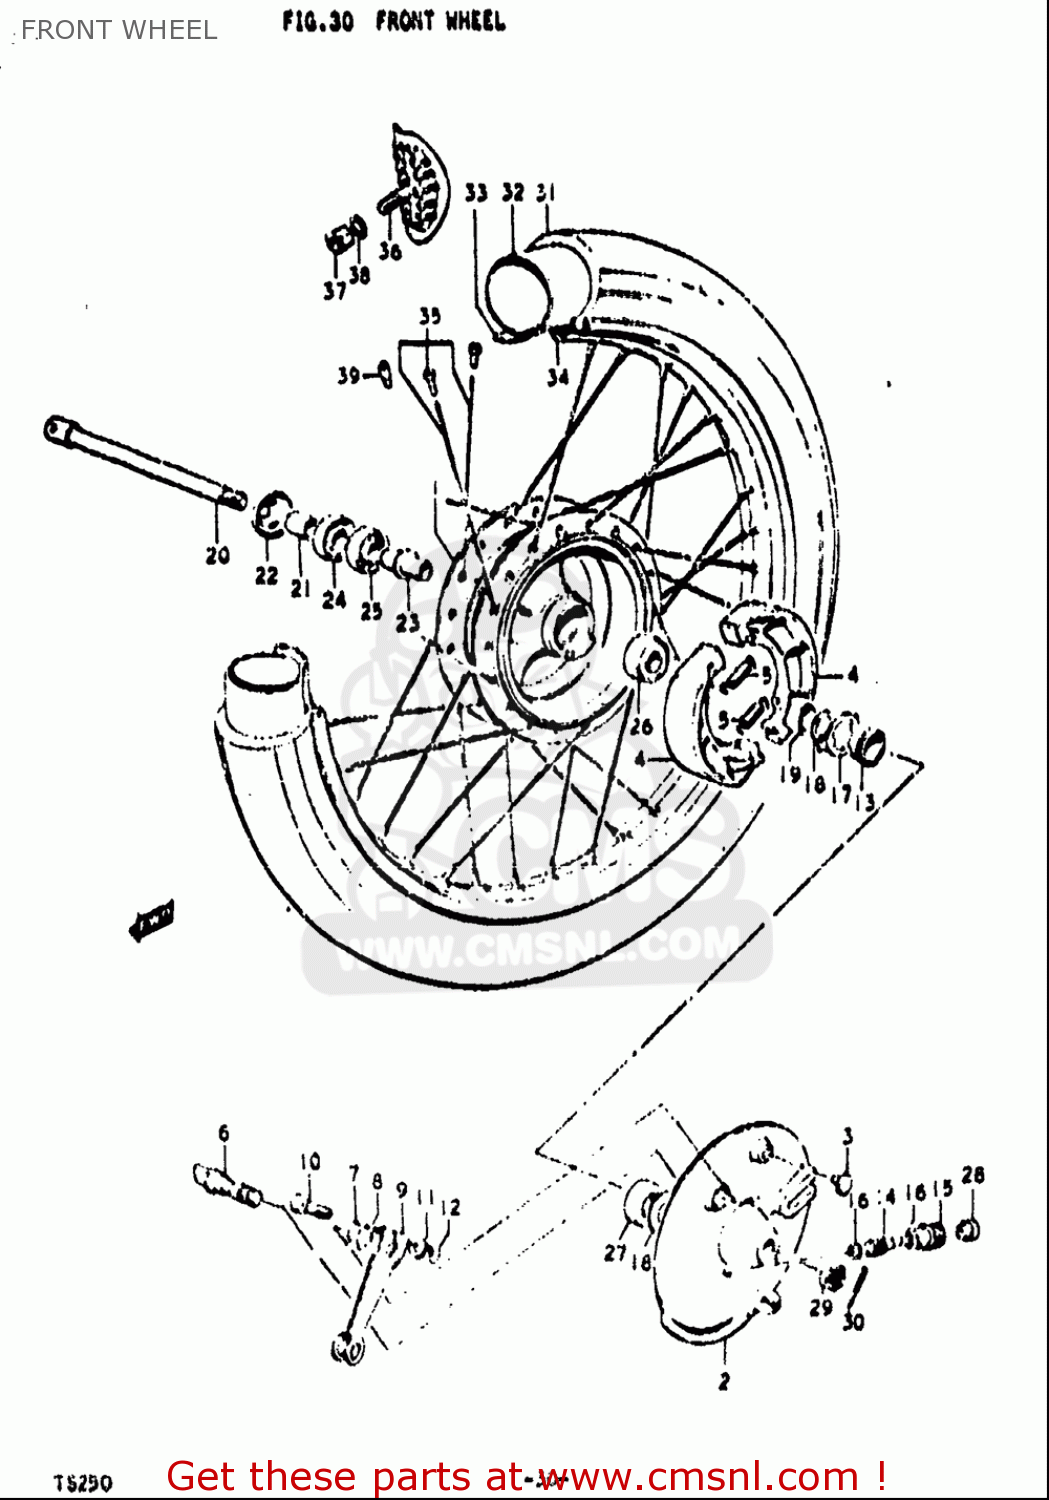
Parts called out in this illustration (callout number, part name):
1	HUB,FRONT
3	CAP(OD:20)
4	SHOE SET,BRAKE (NAS)
5	SPRING,BRAKE SHOE
7	O RING(D:2.4,ID:14.8)
8	WASHER(15.5X24X1.6)
10	BOLT
11	WASHER
12	NUT
14	PINION,SPEEDOMETER
15	BUSHING,SPEEDOMETER PINION
16	WASHER(5.1X9X0.4)
17	DRIVER,SPEEDOMETER GEAR
18	WASHER(22.5X27X1)
19	CIRCLIP
21	SPACER
25	BEARING
26	BEARING
27	SEAL,OIL(26X38X4)
28	SEAL,OIL(6X10X3)
29	NUT
30	PIN 30X40
32	TUBE ASSEMBLY,WHEEL,INNER
33	PROTECTOR,WHL INR TUBE
36	STOPPER,BEAD(1.85)
37	NUT
38	WASHER
39	BALANCER,WHEEL (50G)
